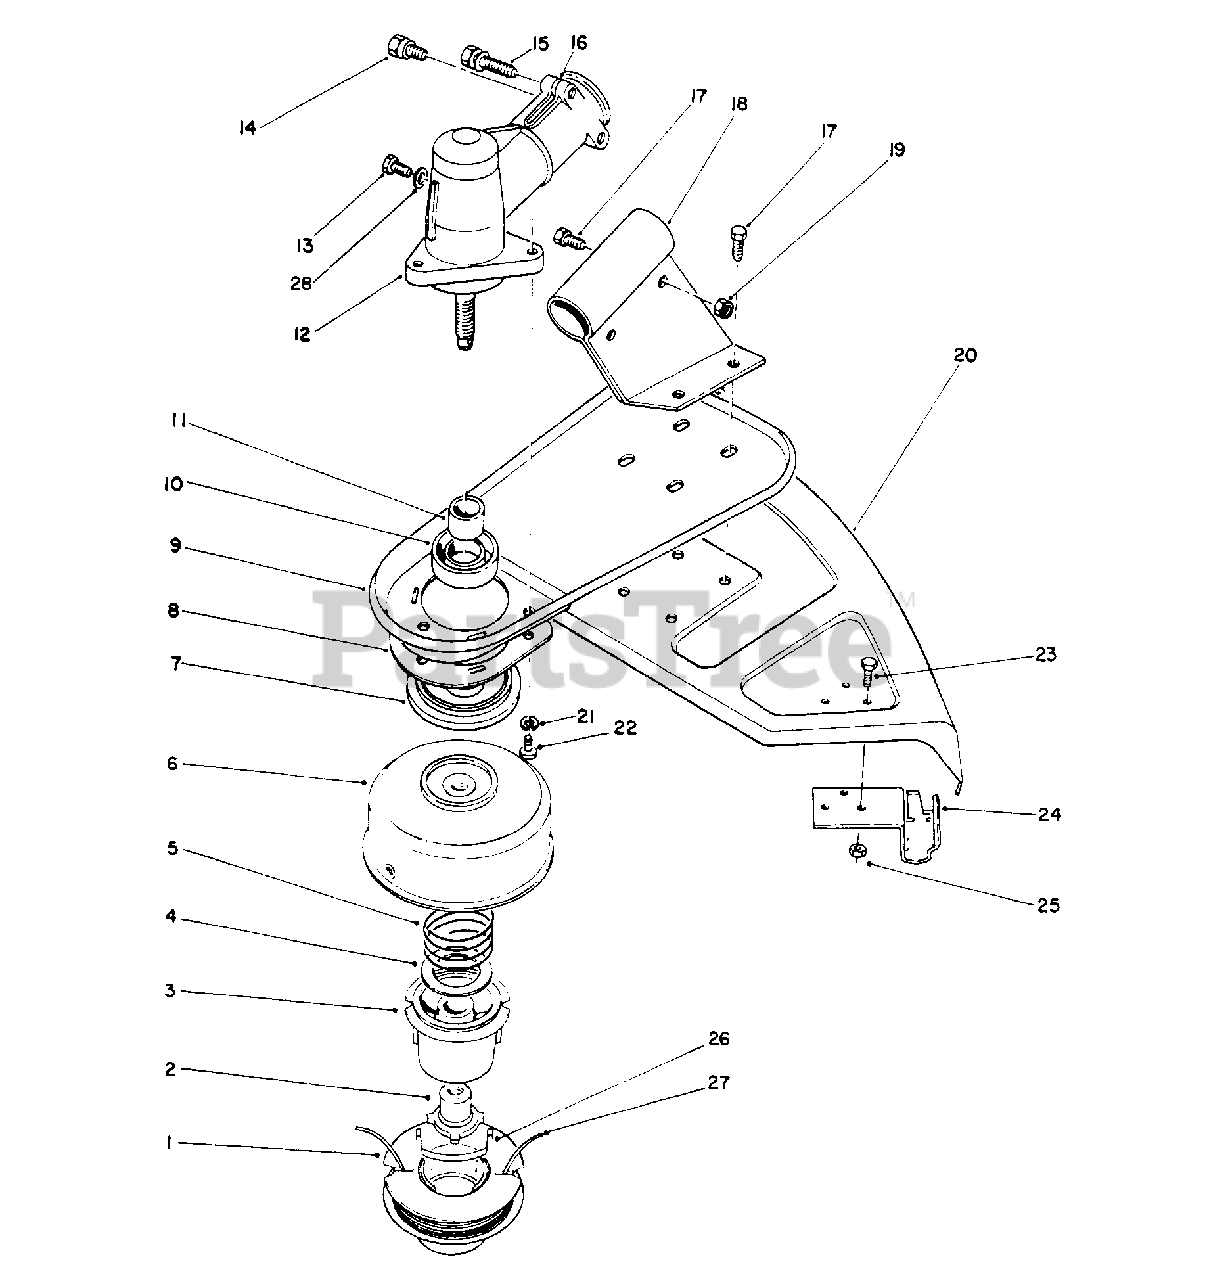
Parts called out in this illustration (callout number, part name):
1	Spool-Prewound .08 Dia. 38' (Incl. Ref. #26)
2	Driver L.H.
3	Core-Spool
6	Drum w/Eyelet
7	Cap-Dust
8	Guard-Grass Wrap
9	Support-Shield
10	Seal-Oil
11	Sleeve-Spline
12	Gear Box Assembly (Incl. Ref. #10, 11, & 13-16)
13	Screw-Hex. Hd.
14	Screw-Hex. Hd.
15	Screw-Hex. Hd.
16	Washer-Flat
17	Screw-Hex. Hd.
18	Bracket-Shield
19	Nut-Lock
20	Shield-Grass
21	Washer-Lock
22	Screw-Guard
24	Bracket & Knife Blade Ass'y (Incl. Ref. #23-25)
25	Nut-Lock
